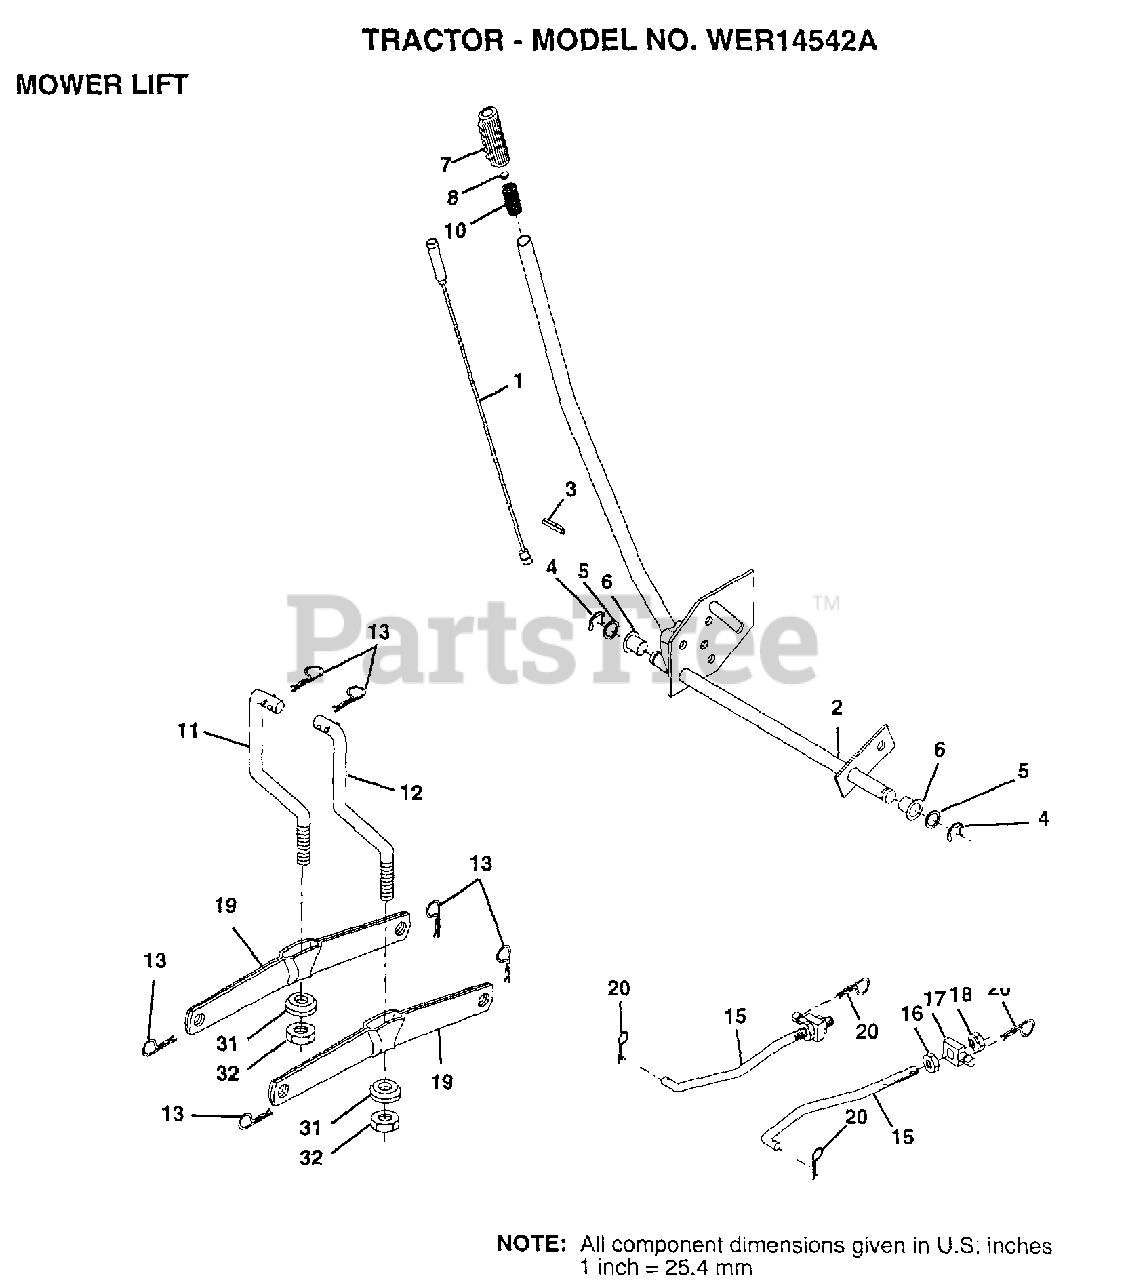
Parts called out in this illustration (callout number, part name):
1	WIRE ASM
2	HANDLE.LIFT.LH.
3	PIN GROOVE
5	WASHER
6	NYLON BEARING
7	CAP T
15	LINK.FRONT
16	NUT
17	TRUNION
18	NUT.LK.W/WSH.1/2.
19	ARM SUSP REAR
20	RETAINER.SPRING
31	BEARING PVT LH
32	NUT.CROWNLOCK.3/8
